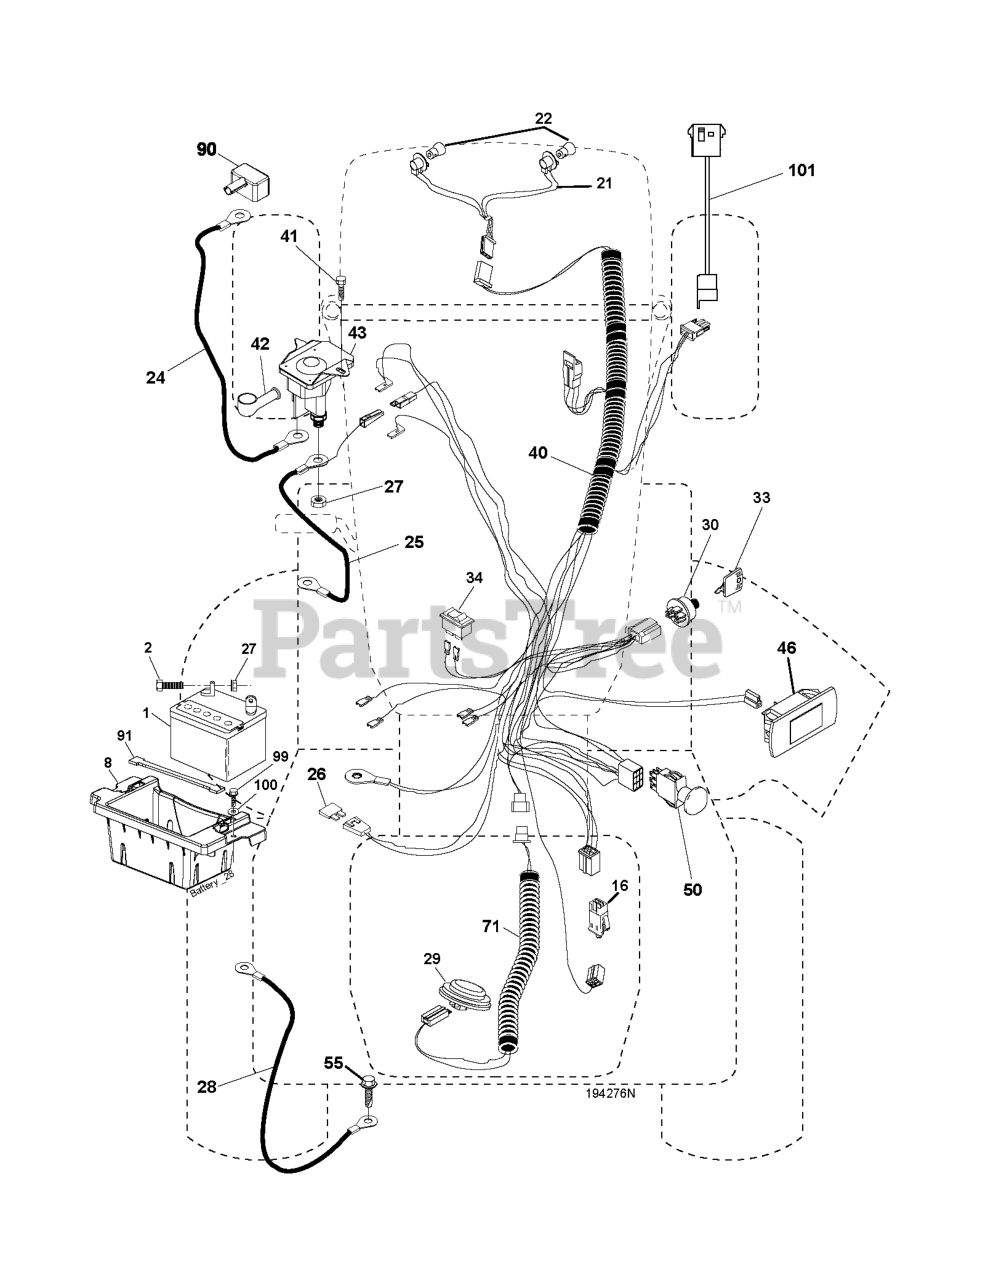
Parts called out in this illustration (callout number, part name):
1	BATTERY 12V .35 AMP
2	BOLT.HEX.1/4.X.3/4.DICHROMATE
8	BOX.BATTERY.MOUNT.FRONT.LT
16	SWITCH INTERLOOK PUSH-IN
21	HARNESS ASSY LIGHT
24	CABLE.BATT.POS.WIRE.TG.DA SOL
25	CABLE.START.RED.17.5".
26	FUSE 20AMP
27	NUT
28	CABLE GROUND 6 GA 21" 90T BLK
29	SWITCH.SEAT.DELTA.OPC.
30	SWITCH.IGN.DELTA.W.LGH.ROS
33	KEY MLD GEN DELTA
40	HARNESS.IGN.DASH.HUQ/P
41	SCREW
42	TERMINAL COVER
43	SOLENOID.W/BRASS.PLUNGER
46	RP.GUAGE.SRVCMNDR.HRMTR.
50	RP.PTO.SWITCH.8 TERMINAL.BLACK
55	Screw 5/16-18 x 1/2 Hex, Self Tapping 5/16-18 x 1/2
71	HARNESS-CHASSIS SUB
90	COVER.TERMINAL.BATTERY
91	STRAP.BATTERY.MOUNT.FRONT(2 2)
99	SCREW HEXWSHR 1/4-20X3/4
101	PIGTAIL.MATNLK.NEW.HAR
